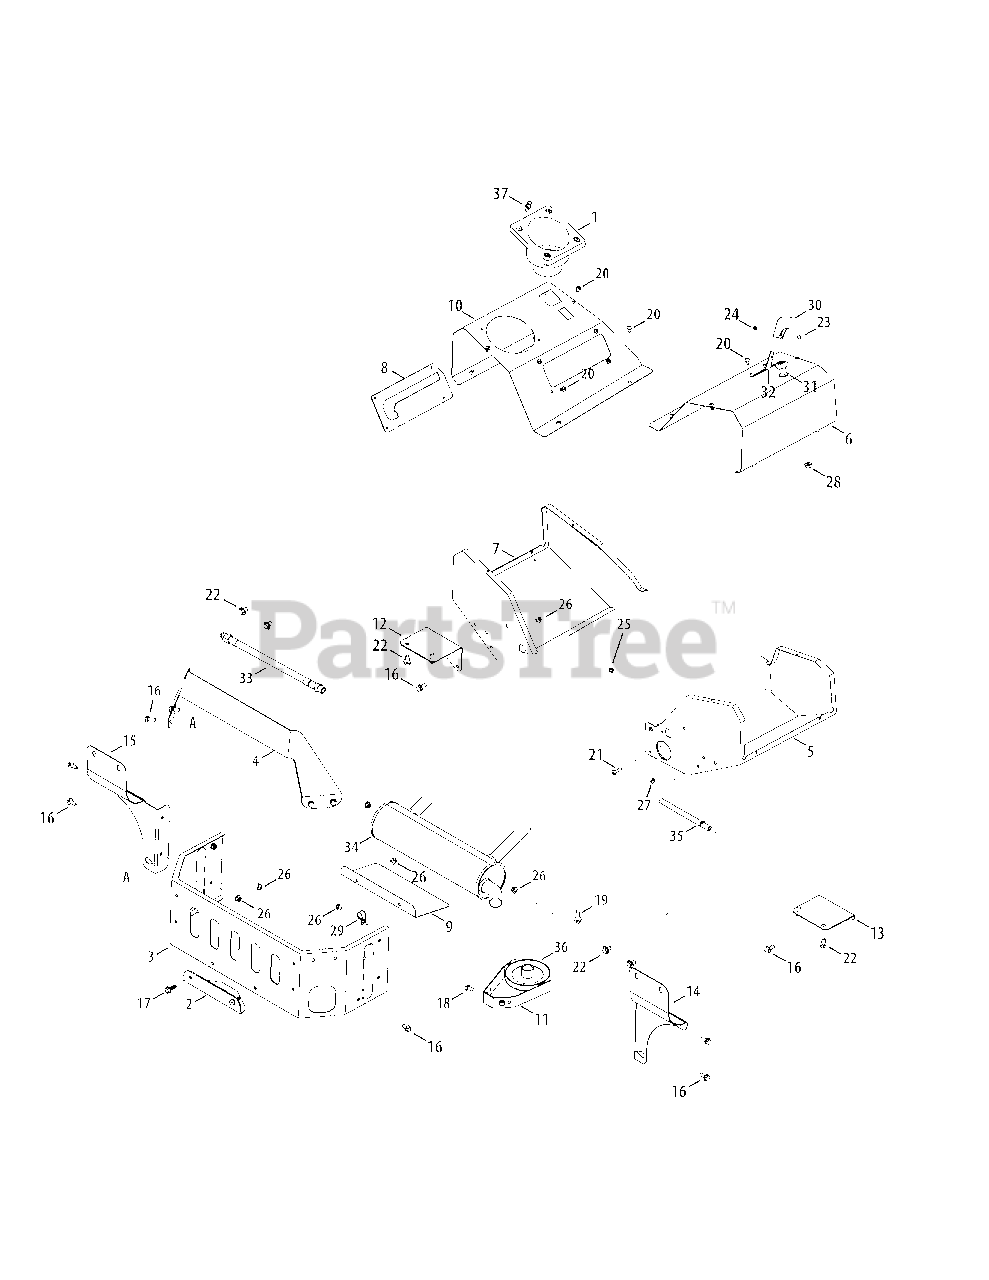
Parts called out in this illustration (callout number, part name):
1	Cup Holder
2	Hitch Bracket
3	Bumper Bracket
4	Upper Bumper Bracket
5	RH Lower Console
6	RH Upper Console
7	LH Lower Console
8	Parking Brake Lock Bracket
9	Muffler Mount Bracket
10	LH Upper Console
11	Belt Keeper Bracket
12	Left Tank Support Bracket
13	Right Tank Support Bracket
14	RH Fuel Tank Support Bracket
15	LH Fuel Tank Support Bracket
16	Hex Screw, 5/16-18
17	Hex Flange, 5/16-18 x 1.0
18	Hex Washer Screw, 5/16-18 x .750
19	Screw, 3/8-16 x 1.00
20	Screw, 1/4-20 x .5
21	Screw, 1/4-20 x 1.0
22	Hex Washer Screw, M10-1.5 x .500
23	Machine Screw, #8-32 x0.375
24	Hex Nut, #8-32
25	Sems Nut, 1/4-20
26	Flange Lock Nut, 5/16-18
27	Flange Lock Nut, 1/4-20
28	Flange Lock Nut, 3/8-16
29	Clamp, 1.0 Dia.
30	Throttle Knob
31	Choke Cable
32	Throttle Cable, 39.0 x .62
33	Oil Drain
34	Kohler Muffler
36	Electric PTO Engine Pulley
37	Plastic Rivet
